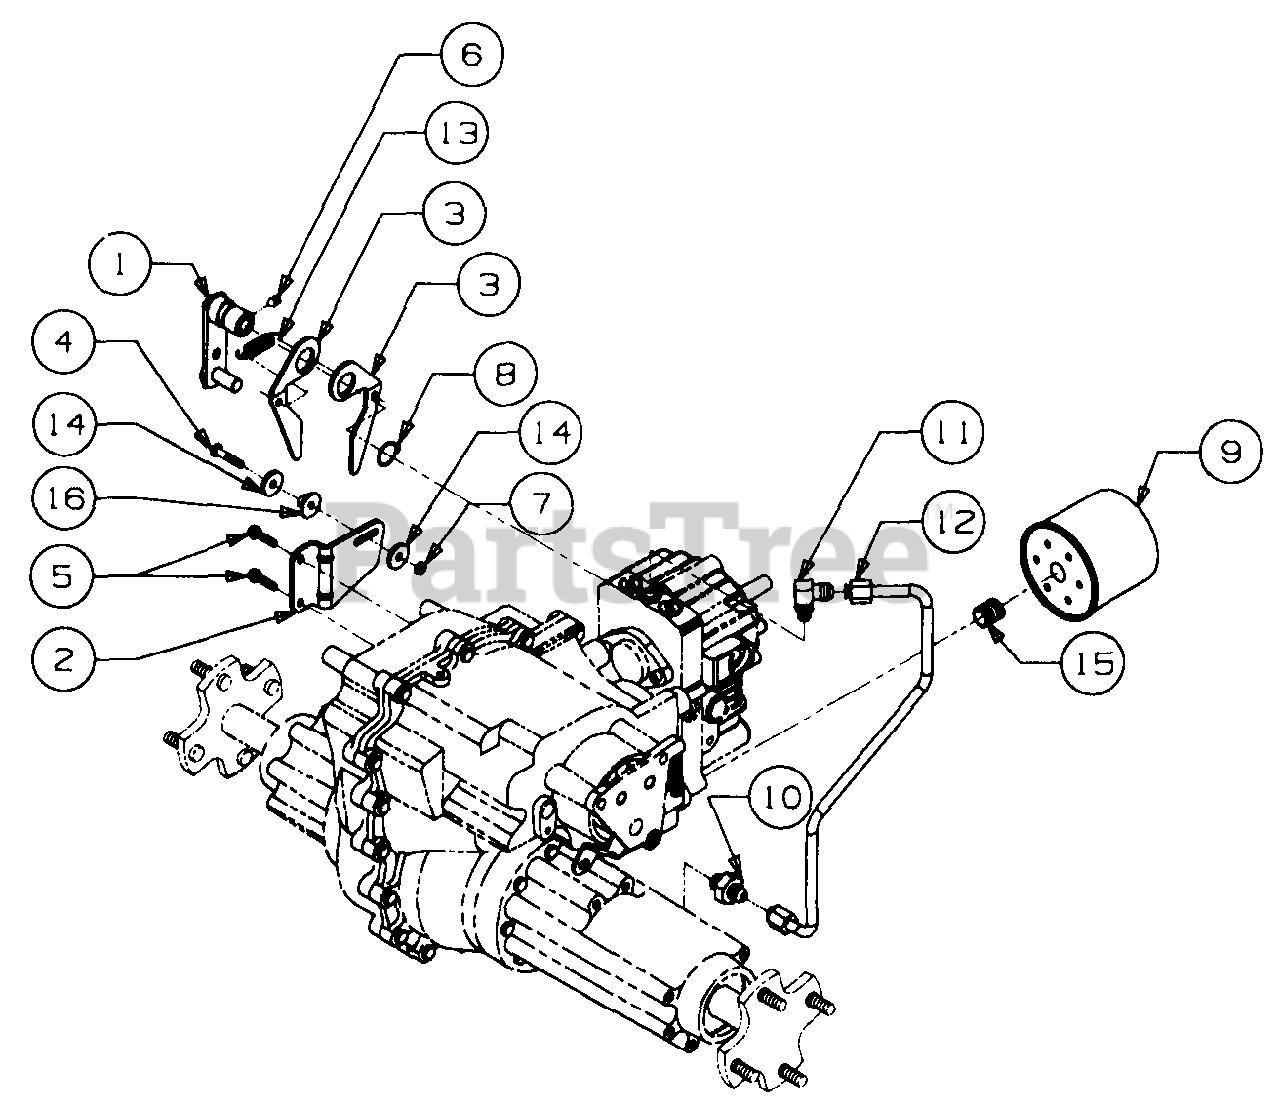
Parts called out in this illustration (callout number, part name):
1	Arm Assy, Control
2	Bracket, Hydro Neutral
3	Arm, Neutral
4	Screw, Hex Cap, 1/4-20 x 1.25 Lg
5	Screw, Hex Wash TT-Tap 1/4-20 x 1.0 Lg
6	Screw w/Patch,Set
7	Nut, Hex Top Lock, 1/4-20
8	Ring, Snap, .875 Shaft
9	Filter, Oil
10	Connector, Tube 37 Deg w/O-Ring
11	Elbow, Adjustable w/O-Ring
12	Tube, Pickup
13	Spring, Extension, .50 OD x 1.97 Lg
14	Washer, Flat, .25 x .93 x .120 Thk
15	Nipple, Oil Filter
16	Spacer, Centering
